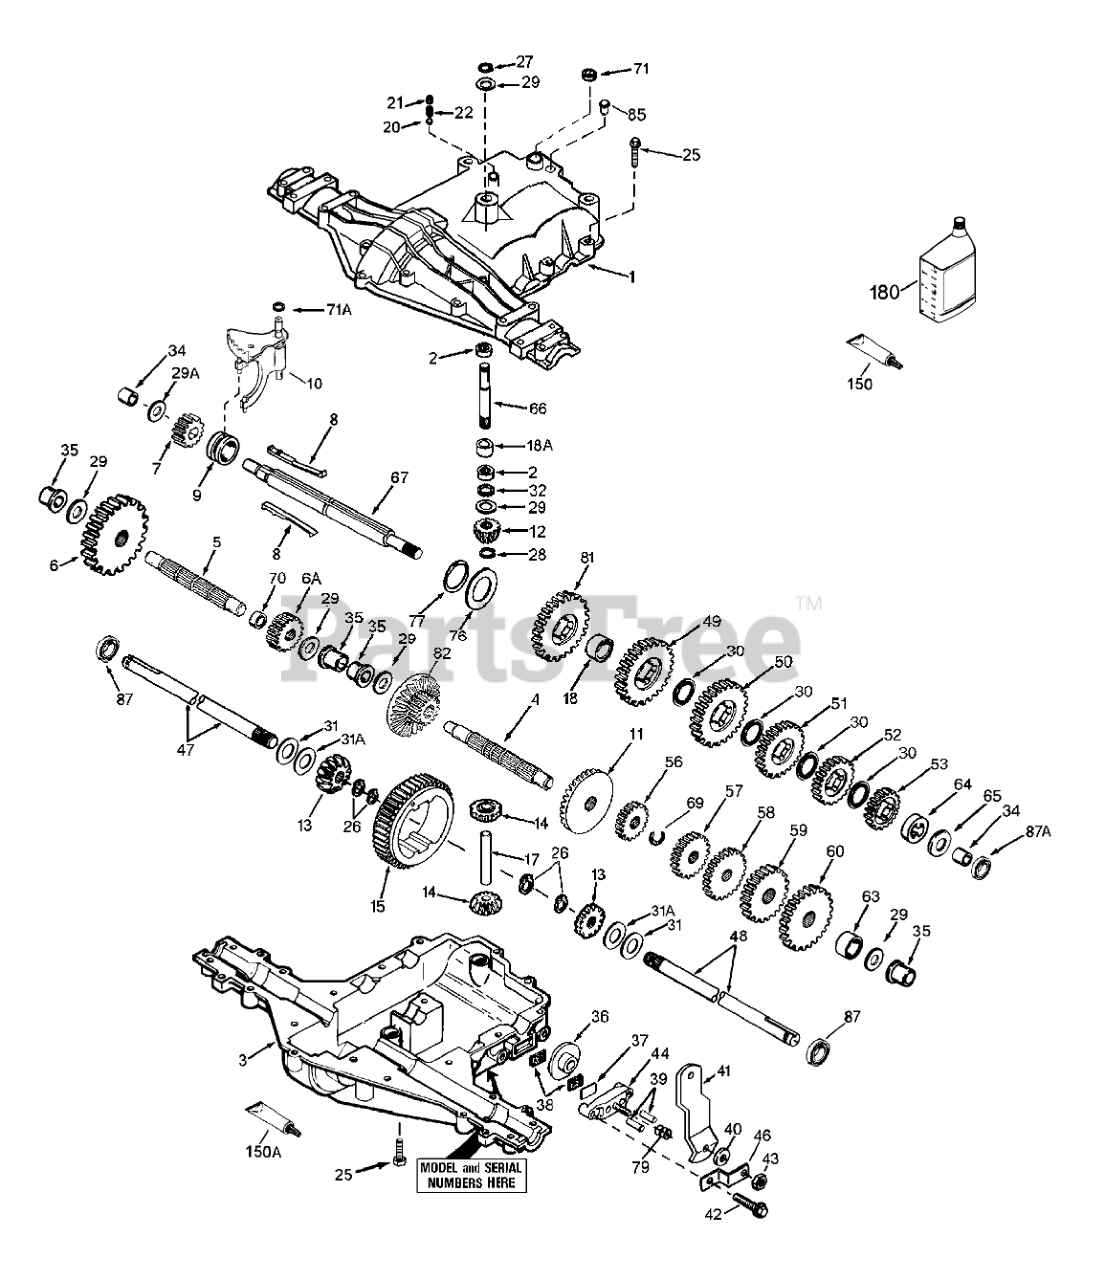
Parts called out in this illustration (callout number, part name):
1	Transaxle Cover
2	Bearing-Needle
3	Transaxle Case
4	Countershaft
5	Output Shaft
6	Spur Gear (38 teeth)
6A	Spur Gear (15 teeth-steel)
7	Spur Gear (11 teeth-steel)
8	Shift Key
9	Shift Collar
10	Shift Rod & Fork
11	Bevel Gear (30 teeth)
12	Input Bevel Pinion (13 teeth)
13	Bevel Gear (16 teeth-steel) (Incl. 14)
14	Bevel Gear (16 teeth-steel) (Incl. 13)
15	Ring Gear (43 teeth)
17	Drive Pin
18	Spacer
18A	Spacer
20	Ball-Steel
21	Screw-Set
22	Spring
25	Ring Set (.020 O S)
26	Retaining Ring (pkg of 2)
27	Ring-Snap
28	Ring-Retainer
29	Washer
29A	Washer
30	Washer
31	Washer
31A	Flat Washer (.062 wide)
32	Oil Seal
34	Bushing
35	Flanged Bushing
36	Brake Disk
37	Brake Pad Plate
38	Pad-Brake 2/Pkg
39	Dowel Pin
40	Washer
41	Brake Lever
42	Ring Set (.020 O S)
43	Locknut
44	Nozzle-Carburetor
46	Bracket
47	Axle (11-15/16" long)
48	Axle (16-1/2" long)
49	Spur Gear (29 teeth-steel)
50	Spur Gear (23 teeth-steel)
51	Spur Gear (20 teeth)
52	Spur Gear (16 teeth-steel)
53	Spur Gear (15 teeth-steel)
56	Spur Gear (11 teeth-steel)
57	Spur Gear (17 teeth-steel)
58	Spur Gear (20 teeth)
59	Spur Gear (24 teeth-steel)
60	Spur Gear (25 teeth)
63	Spacer
64	Spacer
65	Washer
66	Input Shaft
67	Shifter & Brake Shaft
69	Retaining Ring
70	Spacer
71	Cut Seal-Square
71A	"O" Ring
76	Washer
77	Inverted Retaining Ring
79	Piston ASM (.020 O S)
81	Spur Gear (27 Teeth)
82	Bevel & Spur Gear (30 & 13 teeth)
85	Pipe Plug
87	Oil Seal
87A	Oil Seal
150	Liquid Gasket RTV Silicone
150A	Liquid Gasket Loctite #242
180	Gear Oil
